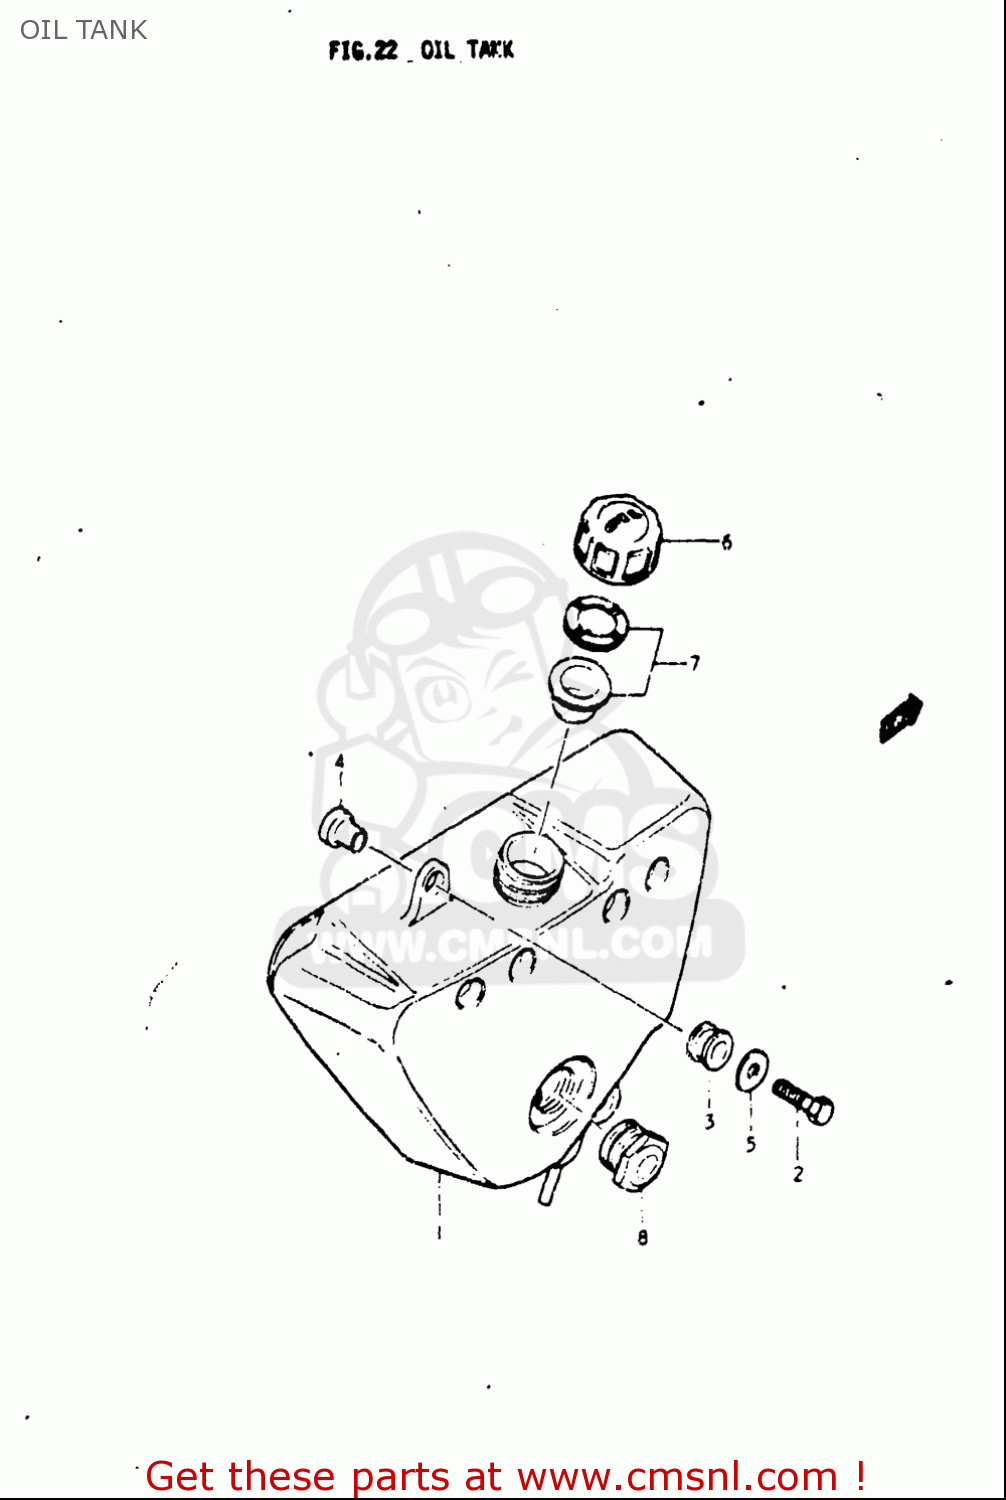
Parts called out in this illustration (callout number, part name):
2	BOLT
3	CUSHION
5	WASHER(6.5X18X1.6)
6	CAP,OIL TANK
7	GASKET SET (NAS)
8	LENS SET,OIL LEVEL
